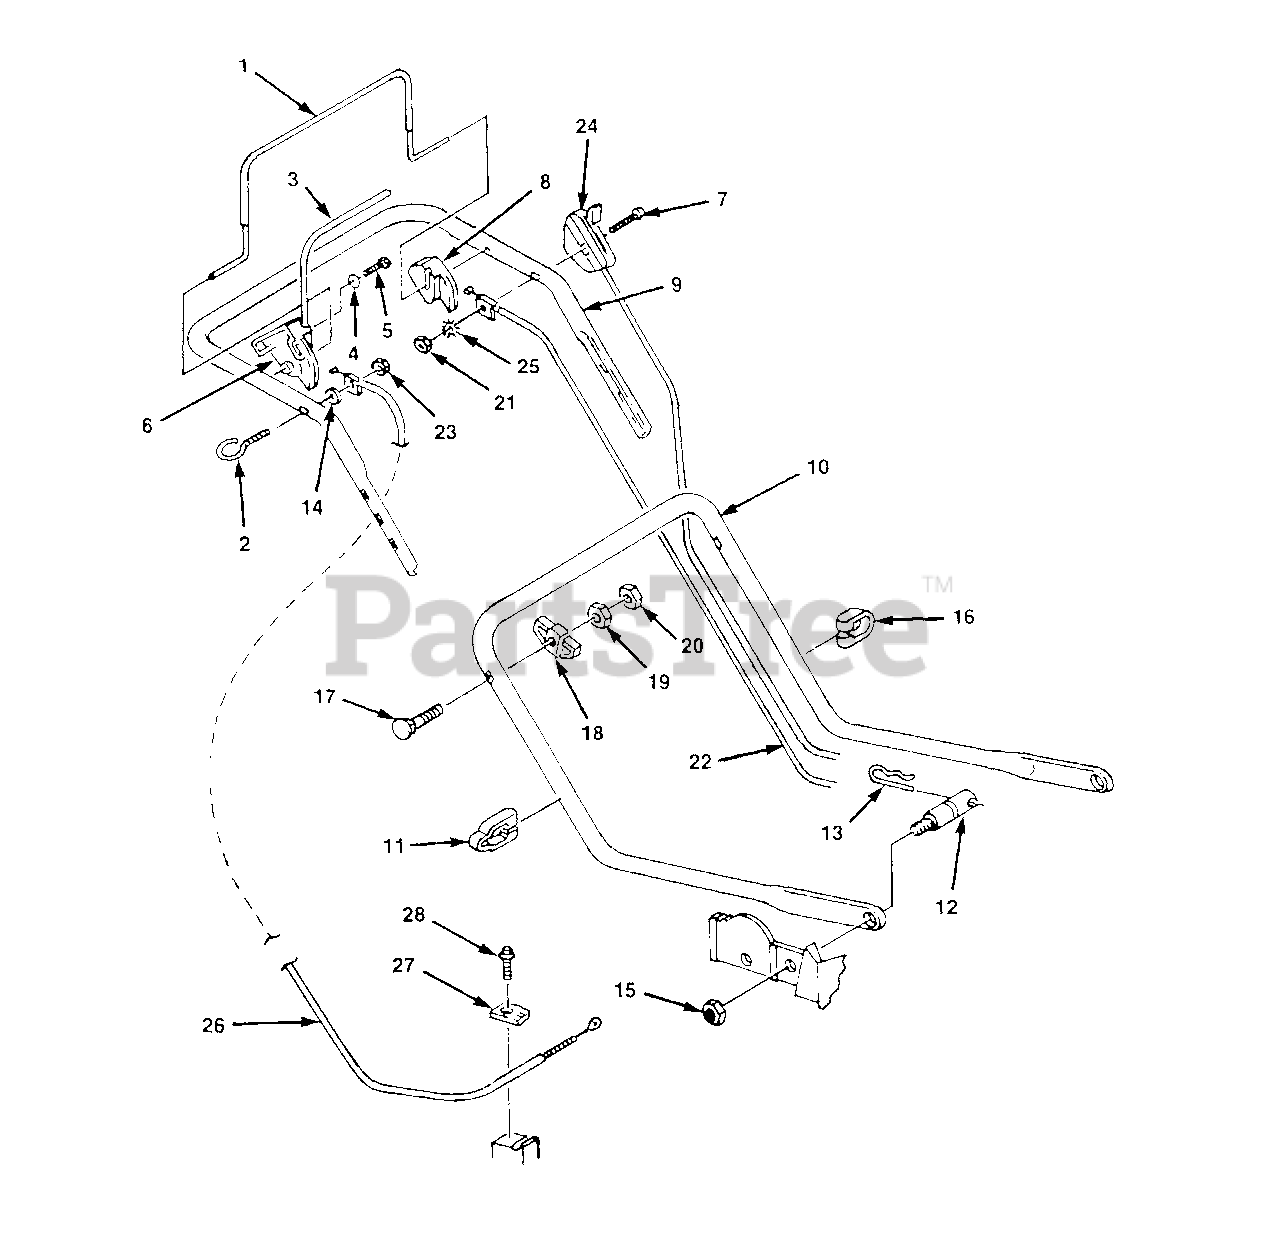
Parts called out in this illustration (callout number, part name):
1	BAIL- Brake
2	EYEBOLT- (1/4-20 x 1.75)
3	TRACTION BAIL
4	WASHER- Flat (1/4")
5	SCREW- Hex (10-16 x 1/2")
6	ACTUATOR- R.H.
7	SCREW- Hex cap
8	ACTUATOR- L.H.
9	HANDLE- Upper
10	HANDLE- Lower
11	CLAMP- Cable (single)
12	STUD- Handle mtg.
13	PIN- Cotter hair
15	NUT- Hex flange (5/16-18)
16	CLAMP- Cable (double)
17	BOLT- Sq. neck
18	KNOB- Handle
19	NUT- Hex (5/16-18)
20	NUT- Hex locking (5/16-18)
21	NUT- Hex (1/4-20)
22	CONTROL- Manual start
23	NUT- Hex locking (1/4-20)
24	CONTROL- Throttle
25	WASHER- Ext. tooth (1/4")
26	CABLE- Traction
28	SCREW- Hex hd. (1/4-20 x 5/8")
